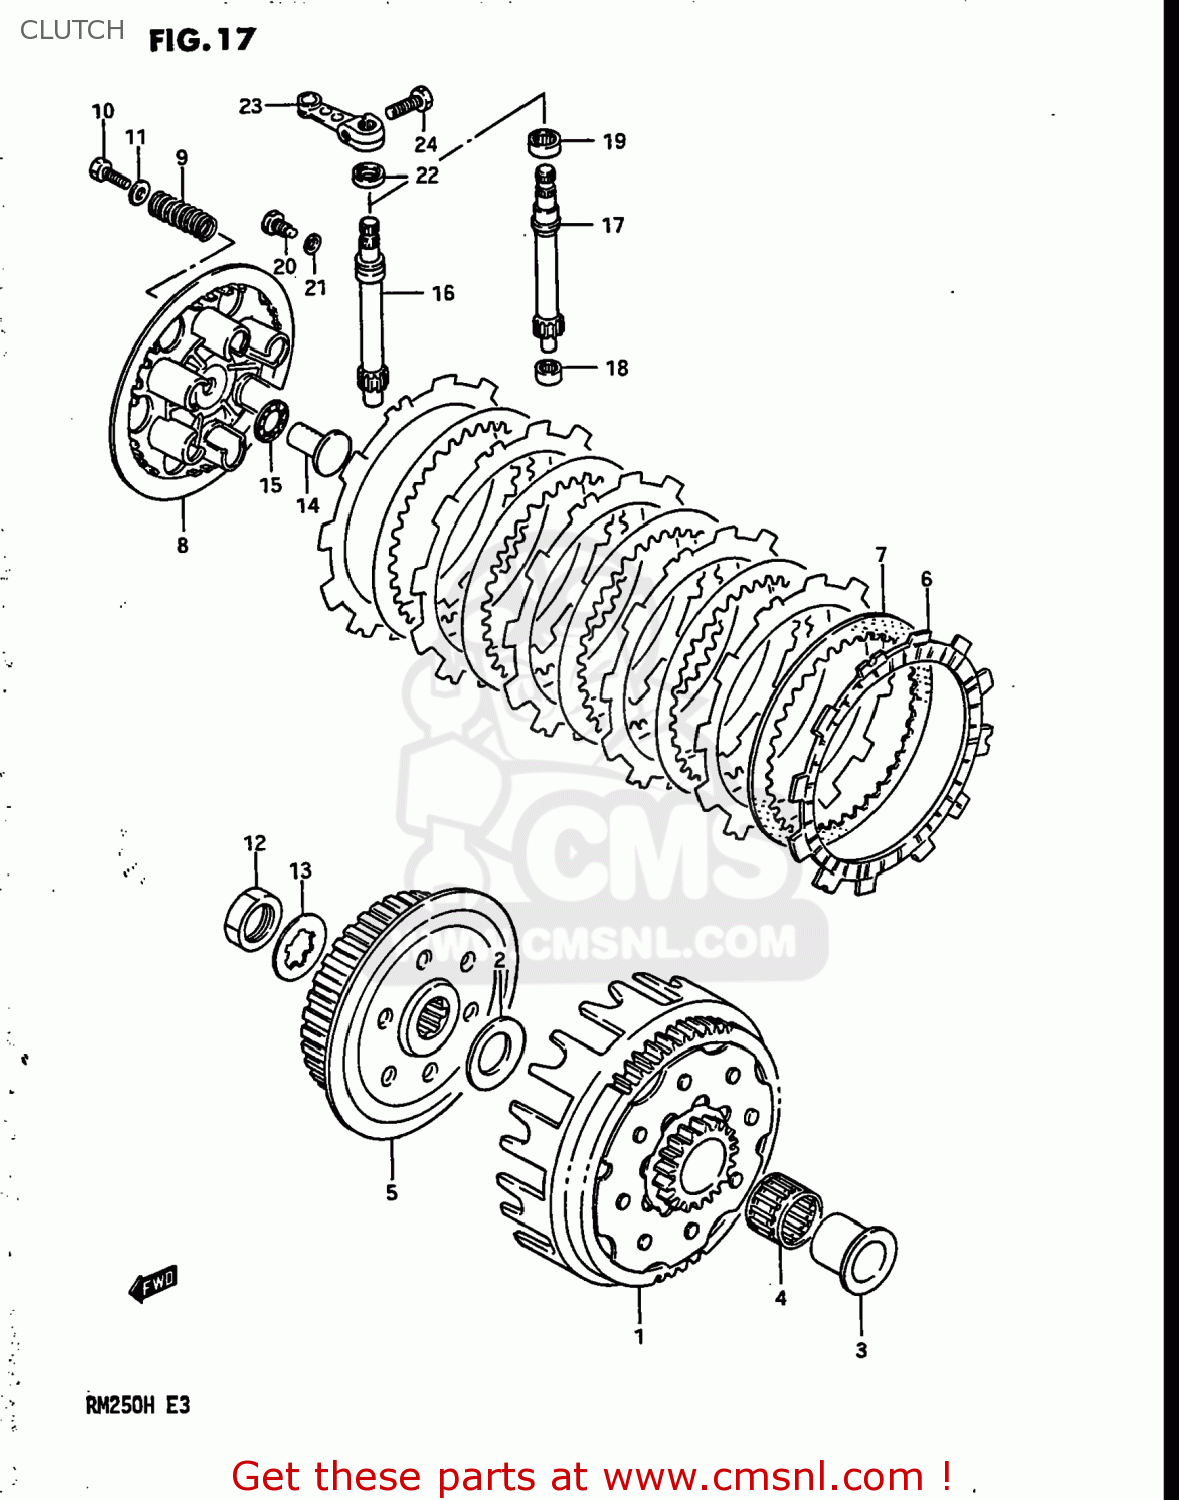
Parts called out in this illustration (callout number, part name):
1	GEAR ASSY,PRI DRIVEN
2	WASHER(20X36X2)
3	SPACER,PRIMARY DRIVEN
4	BEARING(25X30X22)
5	HUB,CLUTCH SLEEVE
6	PLATE,CLUTCH DRIVE
7	PLATE,CLUTCH DRIVEN (NAS)
8	DISC,CLUTCH PRESSURE
9	SPRING
10	BOLT(5X16)
11	WASHER (5.5X16X1.2)
12	NUT (20MM)
13	WASHER,LOCK
14	RACK,CLUTCH RELEASE
15	BEARING(10X22X2.8)
16	PINION,CLUTCH RELEASE
17	PINION,CLUTCH RELEASE(NT:12)
18	BEARING(9X13X10)
19	BEARING(12X16X10)
20	BOLT
21	GASKET(6.2X11X1).2 (NAS)
22	SEAL,OIL(10X17X5)
23	ARM,CLUTCH RELEASE
24	BOLT
